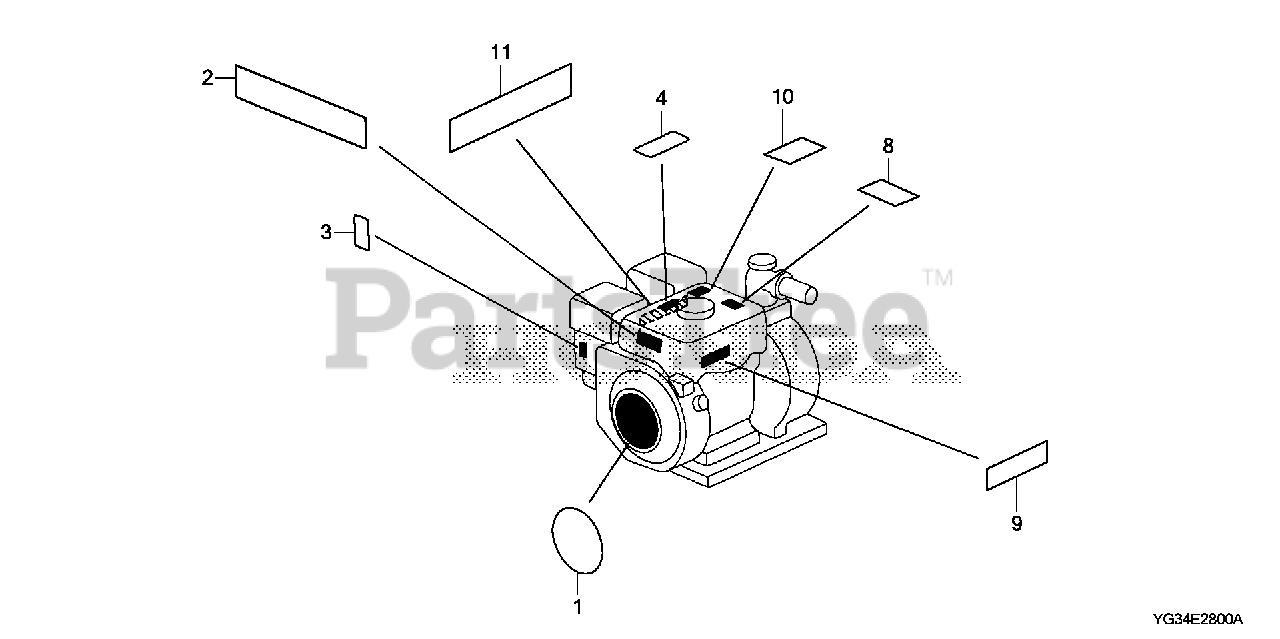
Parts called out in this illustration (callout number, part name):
1	EMBLEM (GX160)
2	LABEL, CAUTION
3	MARK, CHOKE
4	MARK, OIL ALERT (ENGLISH)
